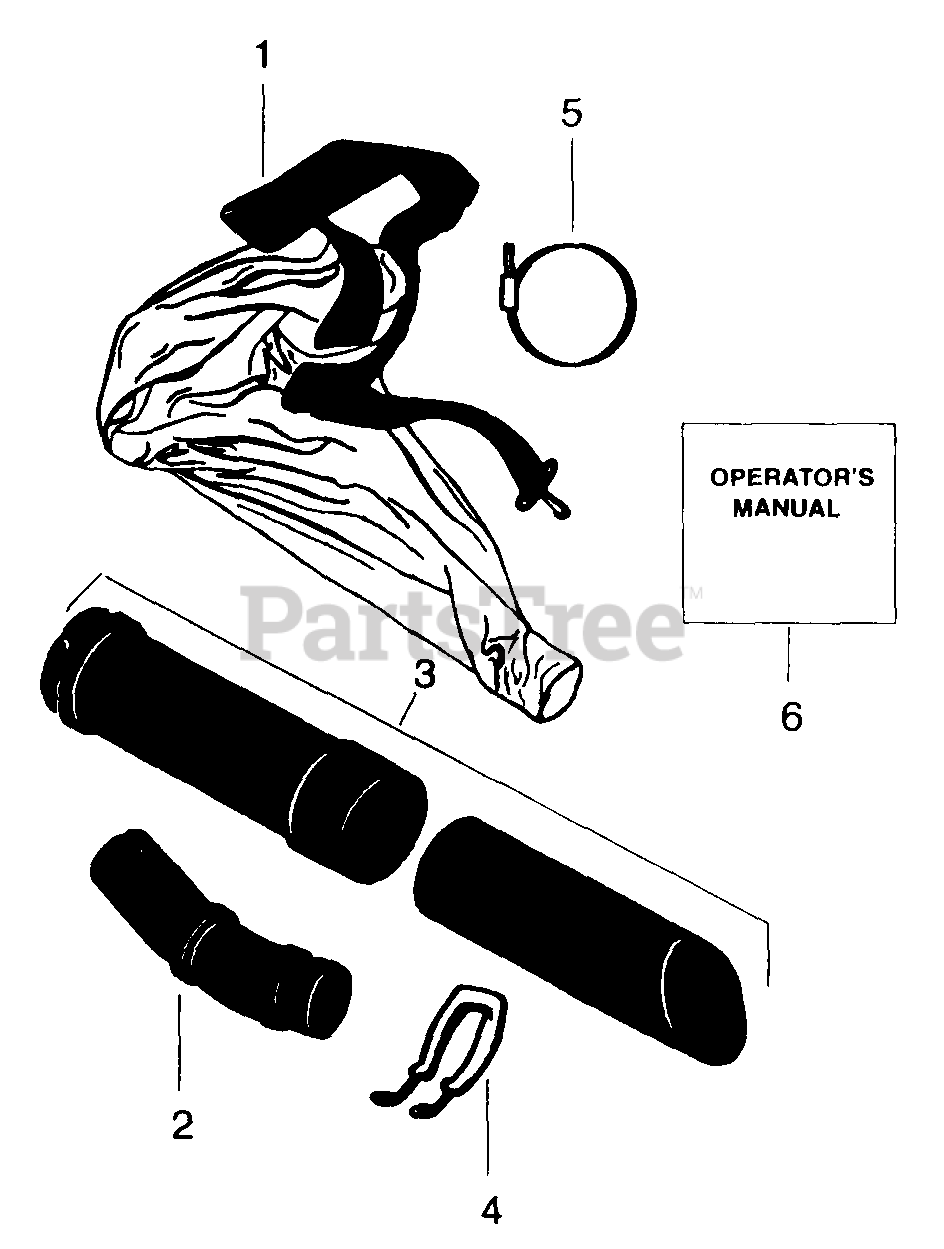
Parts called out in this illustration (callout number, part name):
1	Vac Bag Assy
2	Elbow - Vac Bag
3	Vac Tube Ass'y.
4	Handle - Rear
5	Clamp - Intake Tube
6	Operator Manual
